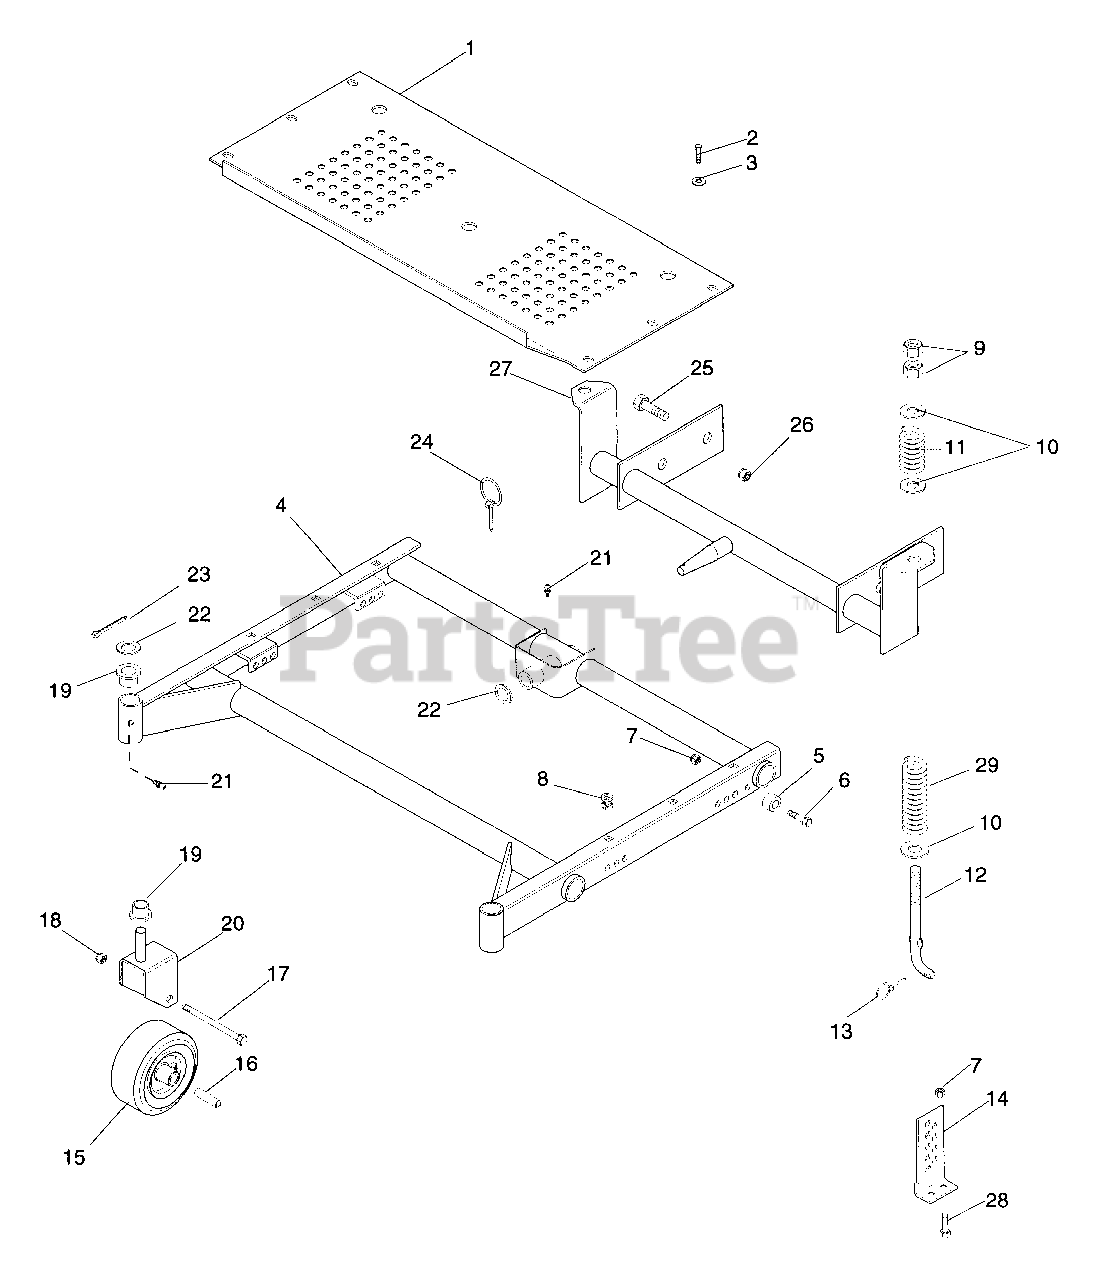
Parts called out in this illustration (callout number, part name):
1	Footboard
2	Scr - Mch .25 - 20 Pan Hd
3	Wshr - Fl - Stl .281 x .625 x .065
4	Wldmt, Mower Frame
5	Bush., 021076 W/E - Coat Finish
6	Blt - Hex .38 - 16 x 1.50 Pl Gr 5
7	Nut - Lk - Nyl .375 - 16 Pl
8	Clip, U - Type Eaton #C17453-1420
9	Nut, 50 - 13 PI
10	Wshr - Fl - Stl .531 x 1.062 x .095
11	Spring-Compression .125 x .78 x 1.00
12	Rod, Height Adj.
13	Pin - Klik 1.000 x.188 x 1.25
14	Brkt, Rear Adj R.H.
14	Brkt, Rear Adj L.M.
15	Whl, Ga 11 x 4 - 4
16	Bush., Caster Fork
17	Bit-Hex .50 - 13 x 6.50
18	Nut - Lk - Nyl .50 - 13 Pl
19	Bshg - Flg 1.020 x 1.75 x .75 Nyl
20	Wldmt, Caster Fork
21	Ftg, Lube, .25 - 28 Self-Thread
22	Brg-R-Thrst 1.002 x 1.552 x .030
23	Pin - Cotr .188 x 1.50
24	Pin - Klik .25 x 1.75
25	Blt - Hex .625 - 11 x 1.50
26	Nut, Lk 5/8 - 11 Hex W/Insr
27	Wldmt, Mwr Frame Mtg
28	Blt - Carriage .38 - 16 x .75
29	Sg.-Comp .095 x .75 x 6.25 Wld 35
